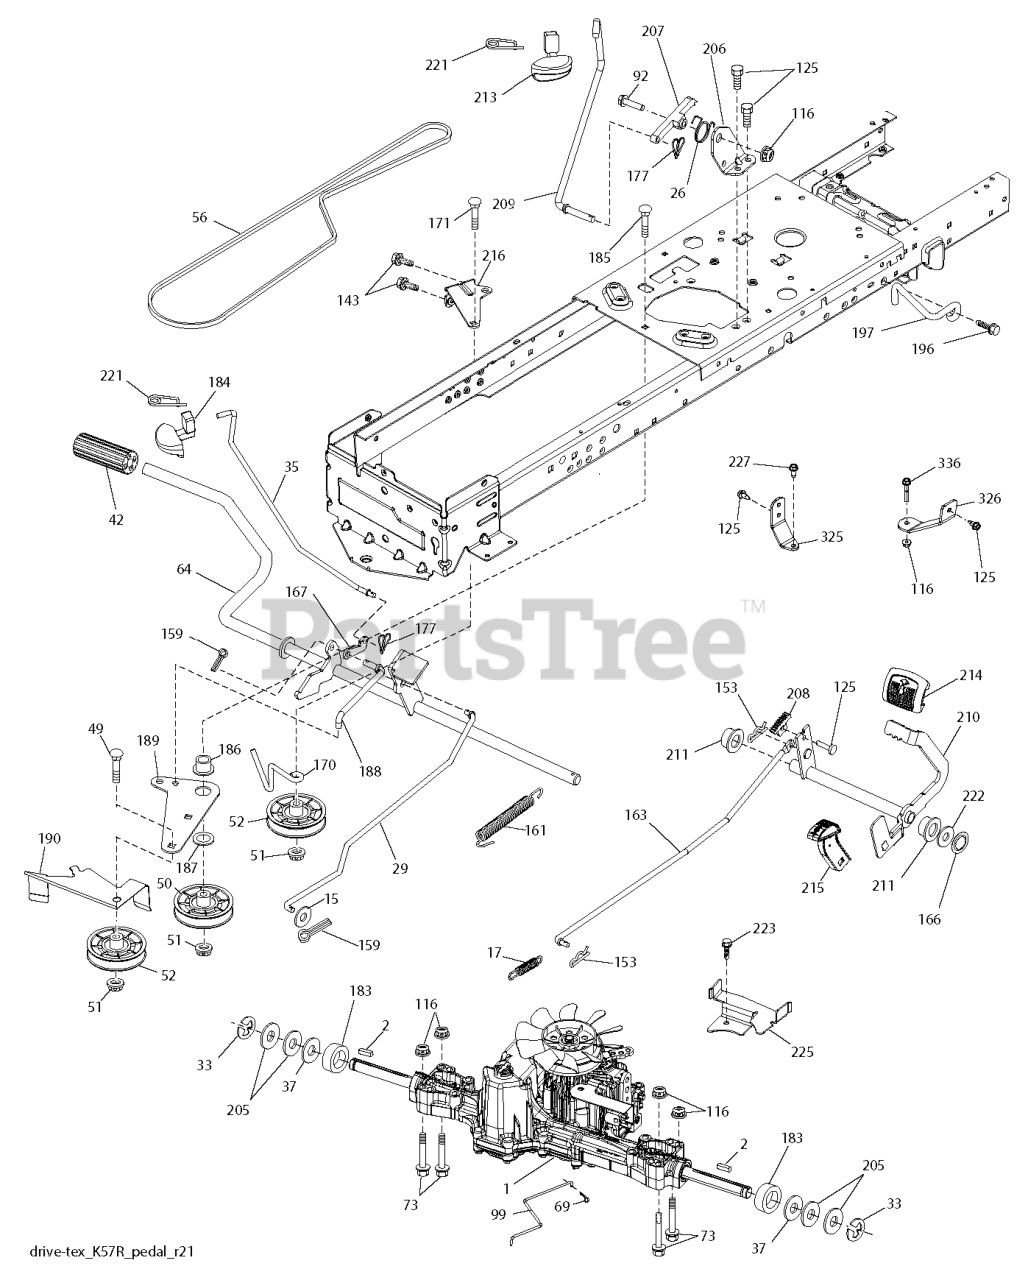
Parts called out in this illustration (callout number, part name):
2	SQUARE KEY
15	WASHER PLAIN WASHER 3/8 X 0.08
17	SPRING.BRAKE.K46.GREEN
26	SPRING.RETURN.CRUISE
29	ROD.BRAKE.K46
37	WASHER.HARDENED
42	PEDAL COVER
50	IDLER.FLAT.910.OFFSET
51	NUT LOCK FLG 3/8-16 UNC
52	IDLER.V-GROOVE.910.OFFSET
64	SHAFT.ASM.PEDAL.BRK.CNTR
69	HAIRPIN.SOFT.ZINC.059X1.125
99	ARM.PIVOTING.TCRD.GEN2.5.BAGGE
125	SCREW
153	RETAINER M
161	SPRING, RETURN LT
166	NUT.PUSH.625
167	LATCH.BRAKE.SPRING
170	KEEPER.V-IDLER.CENTER.
177	PIN COTTER;LOCKING;BOWTIE;1IN
183	SPACER AXLE
184	HANDLE.PARKING.BRAKE.H (BLK)
186	SPACER.RETAINER
188	LINK.CLUTCH.GROUND DRIVE.LONG
189	BELLCRANK.GROUND.DRIVE.TEX.
190	KEEPER.BELLCRANK.DRIVE
196	SCREW 3/8-16X1
206	BRACKET.MOUNT.CRUISE.LATCH
210	ROCKER.ASM.PEDAL.CONTR
211	BEARING.NYLON
213	KNOB.CONTROL.CRUSIE.HU
214	PEDAL.FORWARD.PAD.TEX
215	PEDAL.COVER.REVERSE.CRD.X428BK
216	BRACKET.PULLEY.IDLER.W/TEX
221	RETAINER.SPRING.CLIP.H
222	WASHER 21/32 X 1-1/4 X 10 GA.
225	KEEPER.BELT.TRANSAXLE.K46
325	BRACKET.TRQ.STP.46.20".TIRE.LH
326	BRCKT.PNT.TRQ.STP.46.20TIRE.RH
